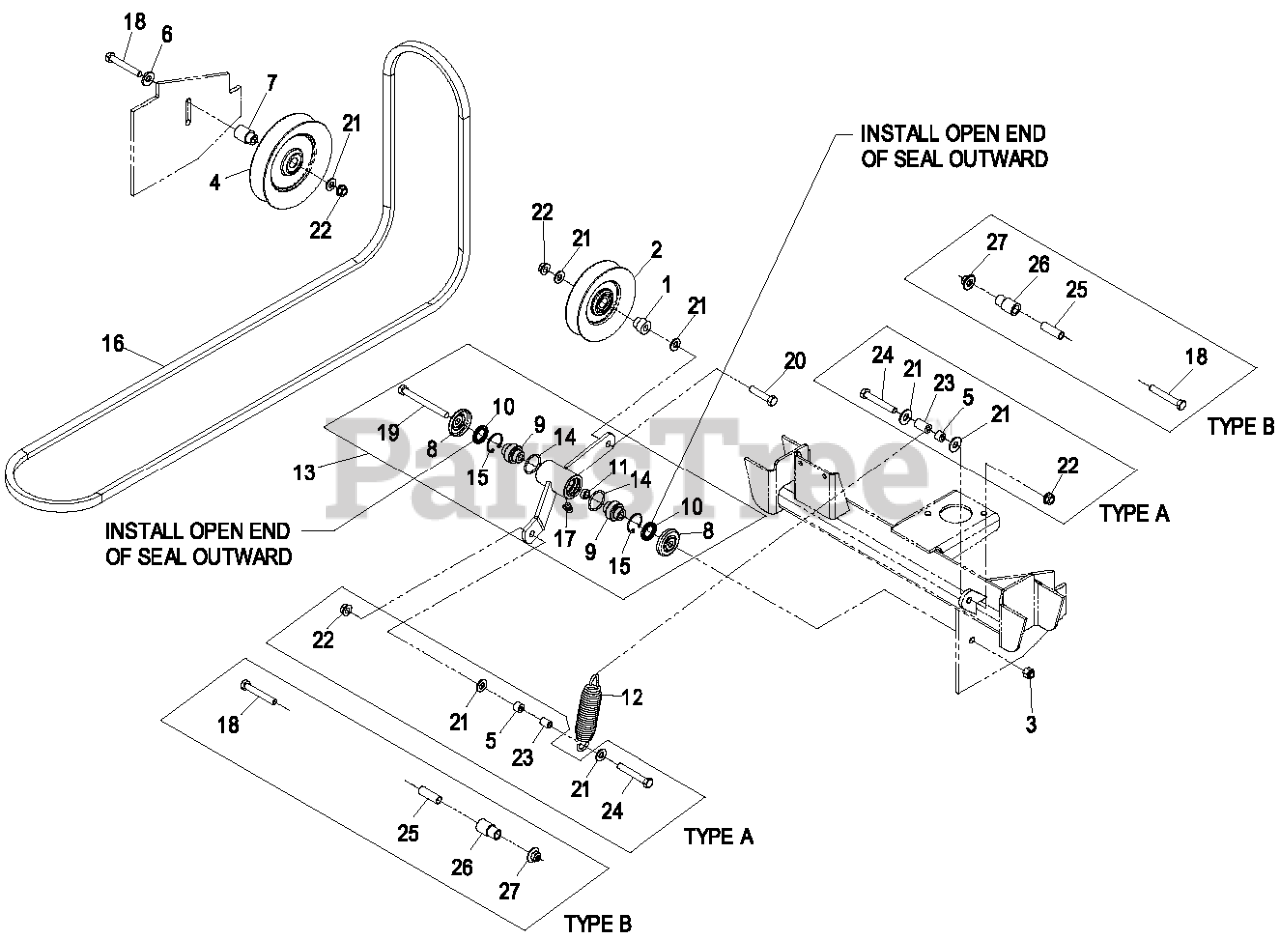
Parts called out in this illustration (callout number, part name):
1	BUSHING-IDLER
2	PULLEY-IDLER
3	NUT-LOCK, NI
4	PULLEY-IDLER
6	WASHER-BELLEVILLE
7	BUSHING-IDLER
8	GUARD-TOP
9	BEARING-SPHERICAL
10	SEAL-LIP, SINGLE
15	RING-SNAP
16	BELT,B 123.2
17	FITTING-GREASE, 90 DEG
18	BOLT-CARR
19	SCREW-HH
20	SCREW-HH
21	WASHER-FLAT
22	NUT-HHF, WHIZ
23	BUSHING-LEVER, LIFT
24	SCREW-HH
26	BUSHING,PLASTIC
27	Nut-Nyloc 3/8-16 Flg
